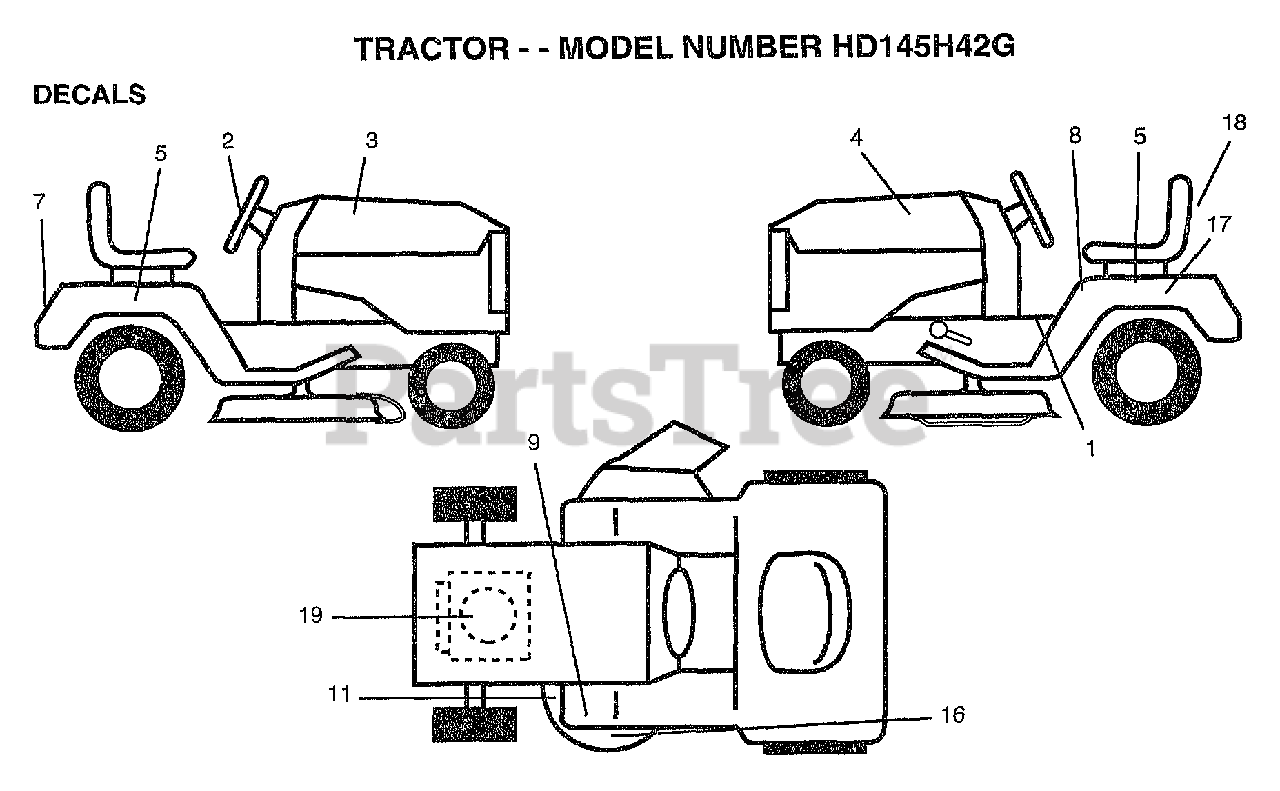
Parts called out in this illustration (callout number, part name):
1	"DECAL-SADDLE,INST"
2	"DECAL WHEEL,STEER"
3	"DECAL-HOOD,RH"
4	"DECAL-HOOD,LH"
5	"DECAL FENDER,SD"
7	"DECAL FENDER,LOGO"
8	"DECAL FENDER,DANG"
9	DECAL CLUT/BRAKE
11	"DECAL-SCHEM,BELT"
16	"DECAL DECK,MULCH"
17	DECAL.BATRY.3-3908
18	"DECAL SEAT,ACC"
19	"DECAL REPLCMT,ENG"
